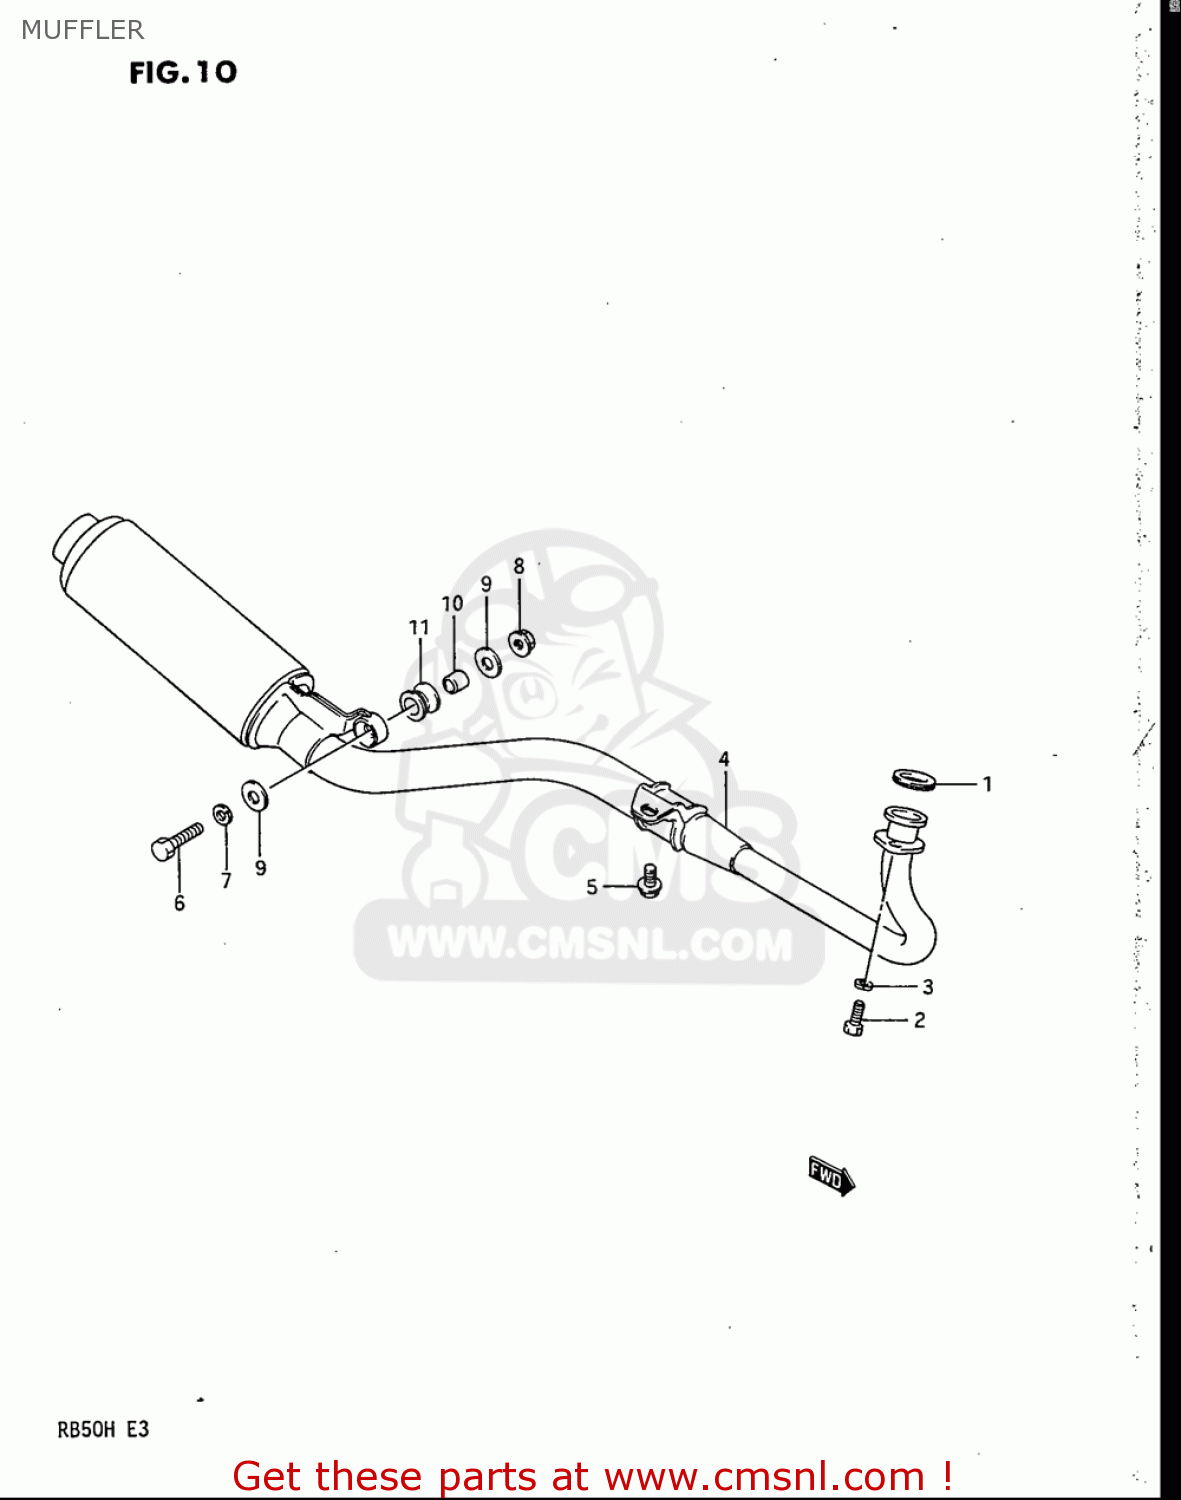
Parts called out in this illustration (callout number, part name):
1	GASKET,EXHAUST PIPE (NAS)
2	BOLT
3	WASHER,LOCK
5	BOLT
6	BOLT
7	WASHER,LOCK
8	NUT
9	WASHER(8.5X26X1.6)
11	CUSHION
